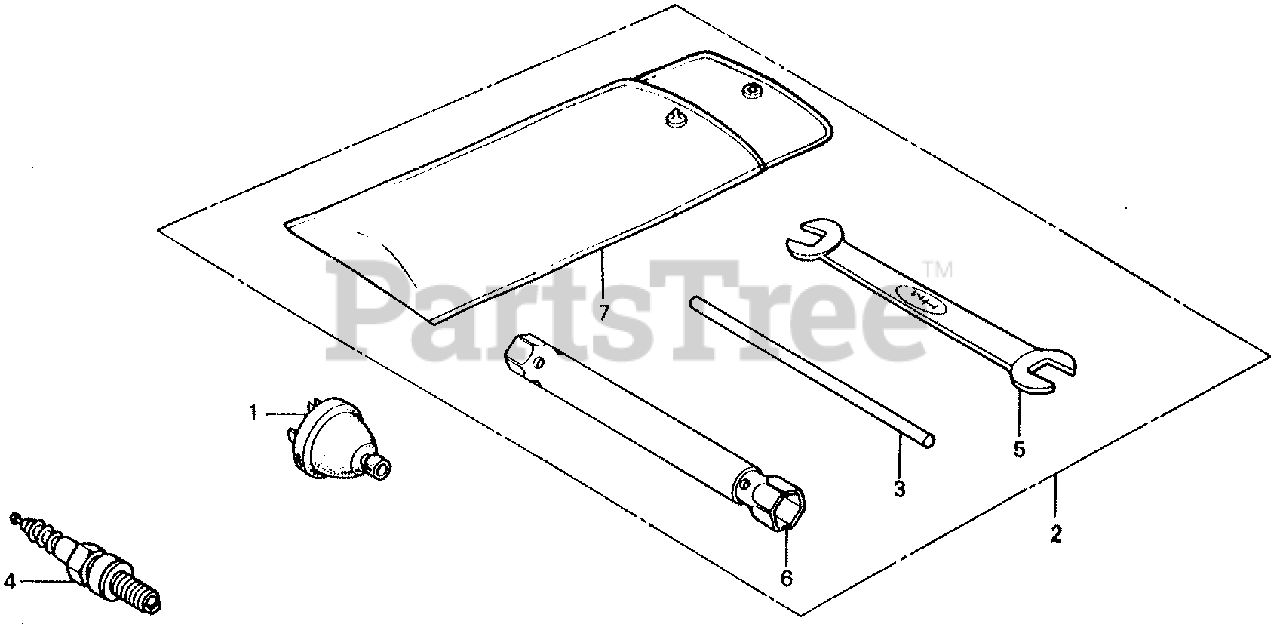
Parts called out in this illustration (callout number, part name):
1	PLUG ASSY., RECEPTACLE
2	TOOL KIT (NOT AVAILABLE)
3	SHAFT, WRENCH (RIKEN)
3	SHAFT, WRENCH (KOWA) (NOT AVAILABLE)
4	SPARK PLUG (BR-4HS) (NGK)
5	WRENCH (10X12) (OPEN END)
6	WRENCH, BOX (P21)
